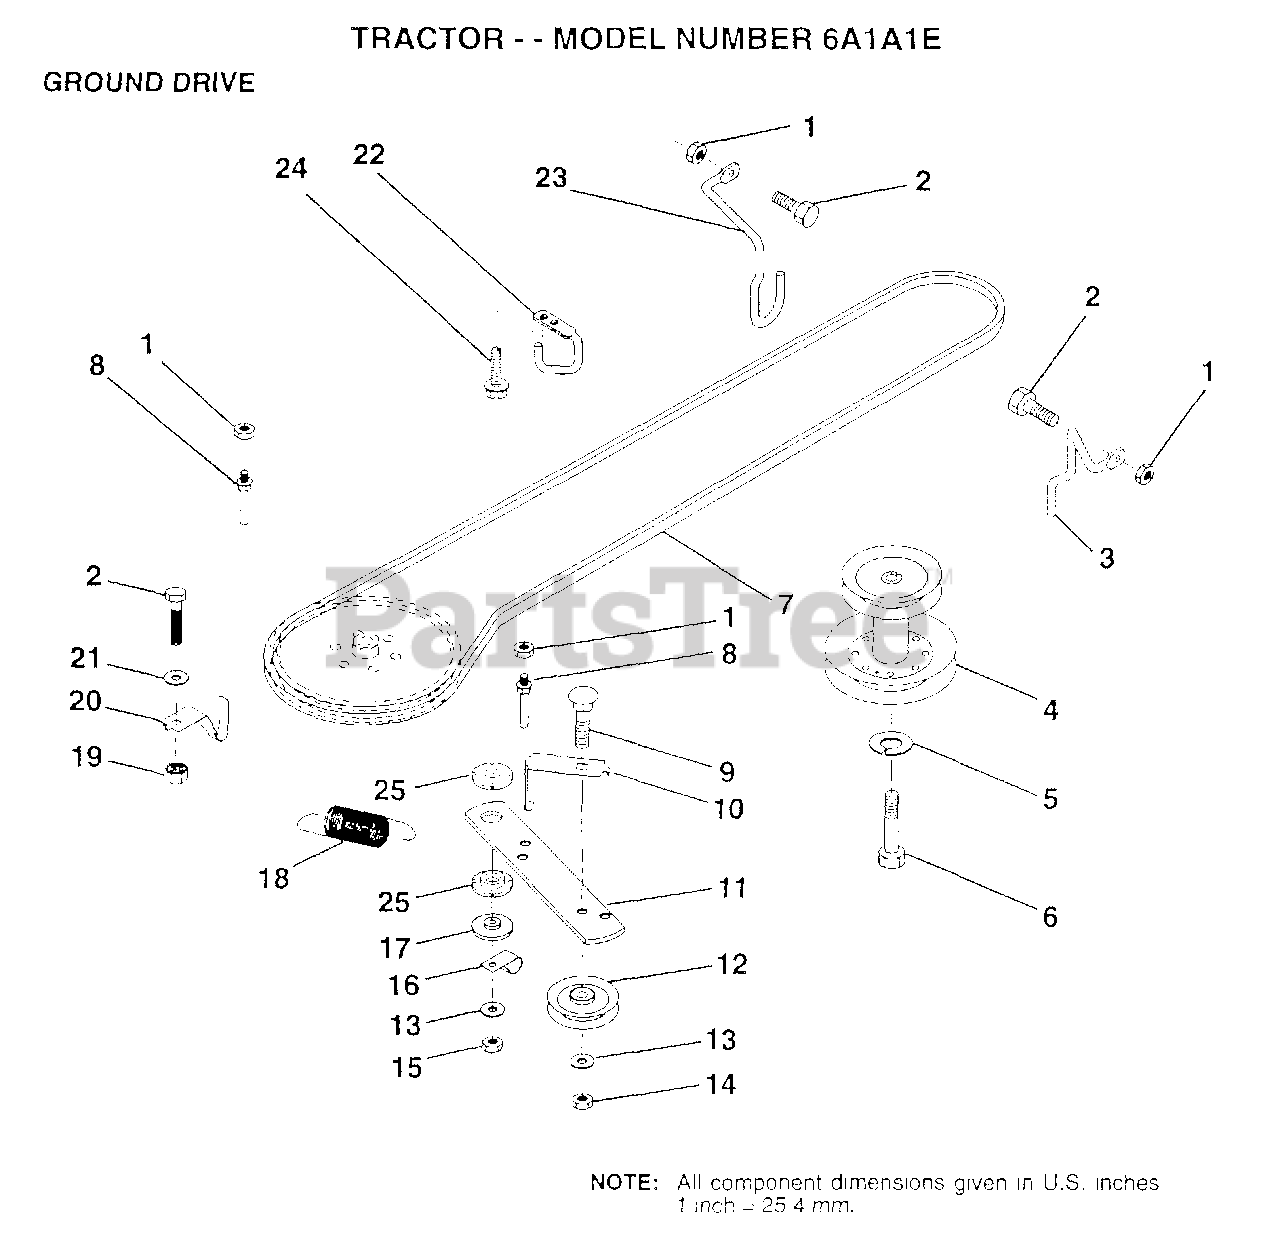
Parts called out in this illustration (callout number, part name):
2	BOLT
3	KEEPER RH
4	PULLEY.ENGINE.LR
5	LOCKWASHER
6	HEX BOLT
7	BELT
8	"KEEPER,DRIVE BELT"
9	BOLT
10	"KEEP,IDLER DR BEL"
11	ARM-IDLER.DR.GRND
12	PULLEY.IDLER.FLAT
13	WASHER
14	LOCKNUT
16	"CLIP,INSULATOR"
17	SPACER
20	KEEPER.BELT.T/A
21	WASHER
22	"KEEPER,FRA DR BEL"
23	KEEPER MOWER LH
24	SCREW
25	BUSHING.NYLON
